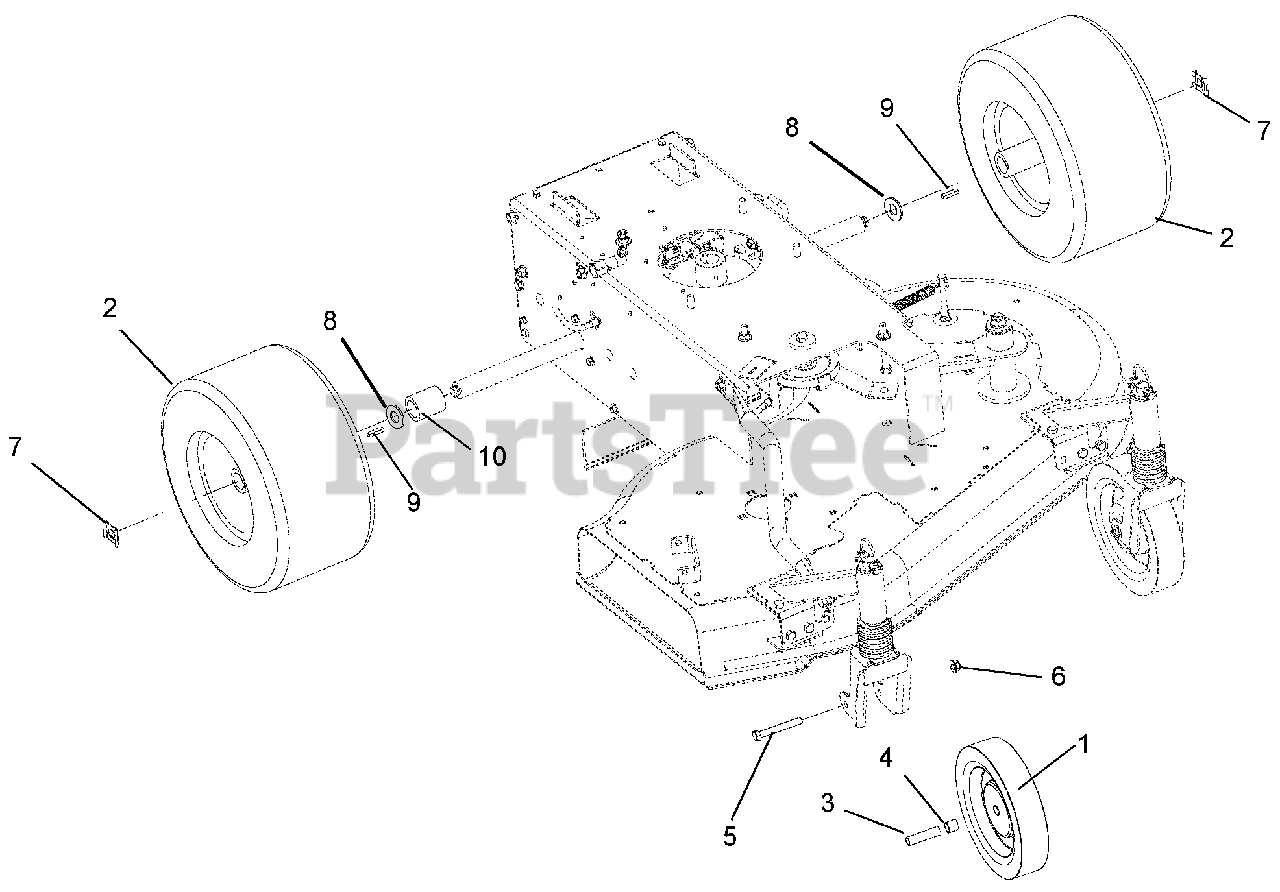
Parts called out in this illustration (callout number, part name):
1	WHEEL, 8.0 X 1.75 X .50
2	ASSY, TIRE/WHEEL 6X13
3	SPCR, WHEEL .385X.500X2.00
4	SPACER-WHEEL
5	@BLT-HEX .38-16X2.75 GR5 YWZC
6	@NUT-LK-NYL-FLG .38-16 YWZC
7	CLIP, SNAP .625 DIA
8	@WSHR-FL-STL.656X1.31X.095 YWZ
9	KEY-RECT .25X.188X1.00
10	SPACER, 1.0X1.5X1.57
